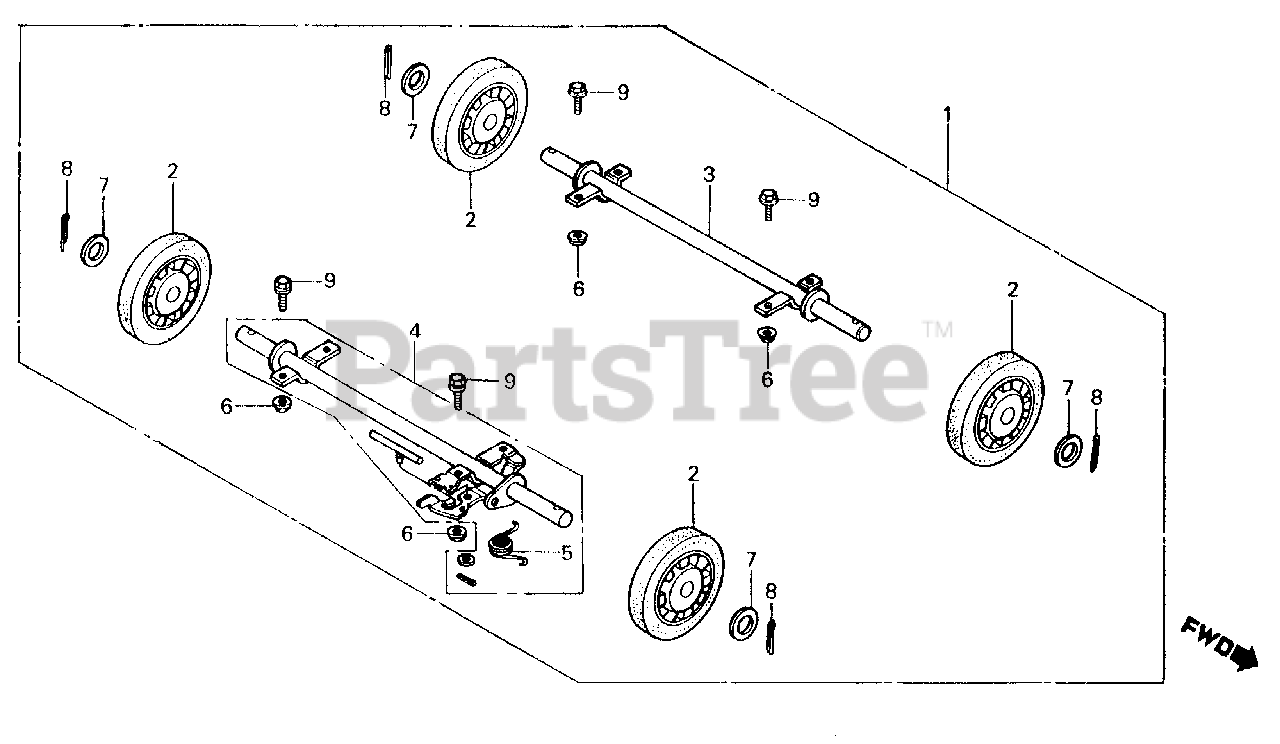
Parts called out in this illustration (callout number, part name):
1	WHEEL KIT (4-WHEELS)
2	WHEEL
3	SHAFT, R. WHEEL
4	SHAFT ASSY., L. WHEEL
5	SPRING, WHEEL STOPPER
6	NUT, FLANGE (8MM)
7	WASHER, FLAT (20MM)
8	PIN, COTTER (4.0X30)
9	BOLT, FLANGE (8X16)
